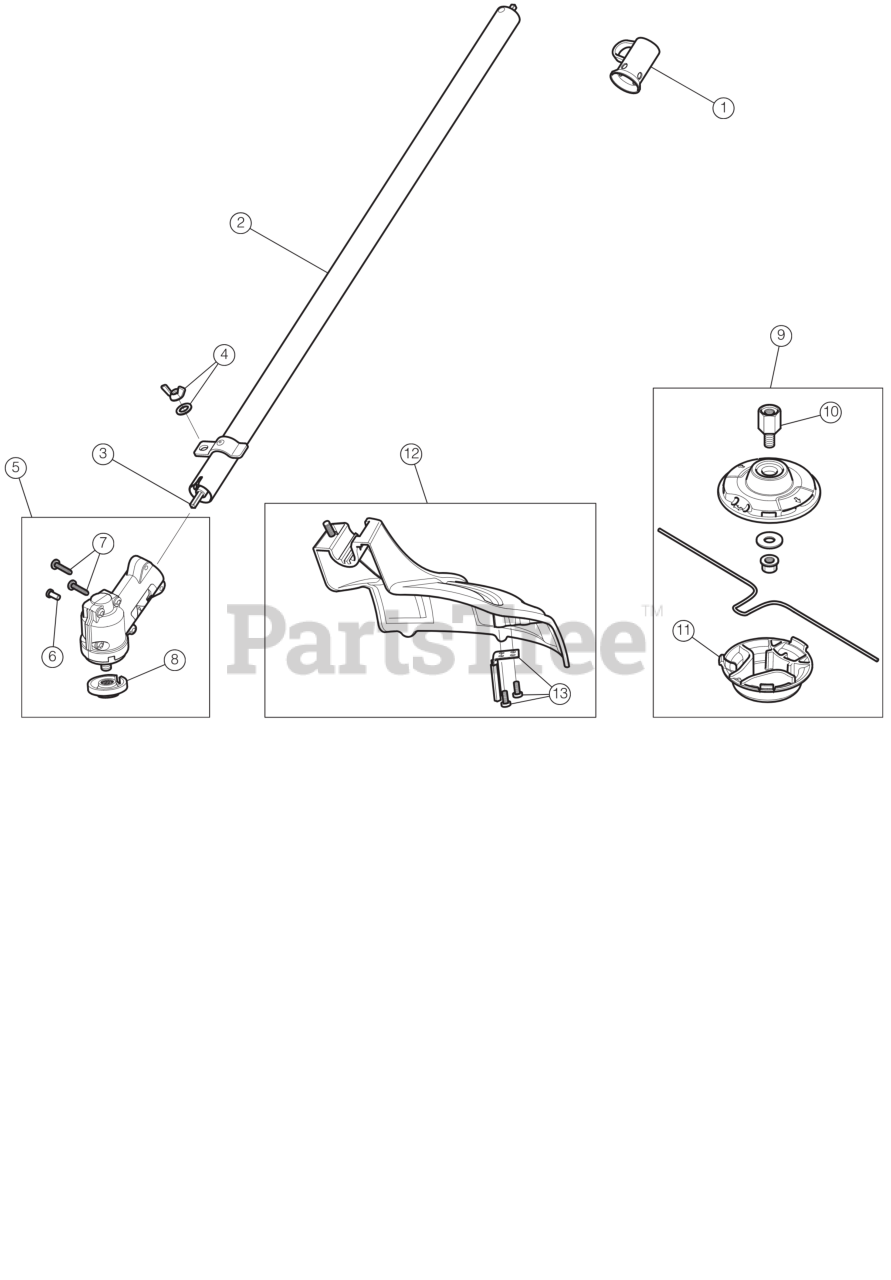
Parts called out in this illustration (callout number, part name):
1	HANGER
2	LOWER BOOM 34.375 (BLACK)
3	FLEX SHAFT LOWER
4	BLADE GUARD MOUNTING HARDWARE
5	GEARBOX LCBC
6	SCREW, 8-32 x .312 P
7	SCREW #10-24X11/16 T-25
8	CUTTING HEAD SPACER
9	CUTTING HEAD ASSEMBLY
10	SPACER GEARBOX
11	HEAD FIXED LINE BT
12	GUARD/BLADE ASM
13	BLADE ASSEMBLY W/HDW
